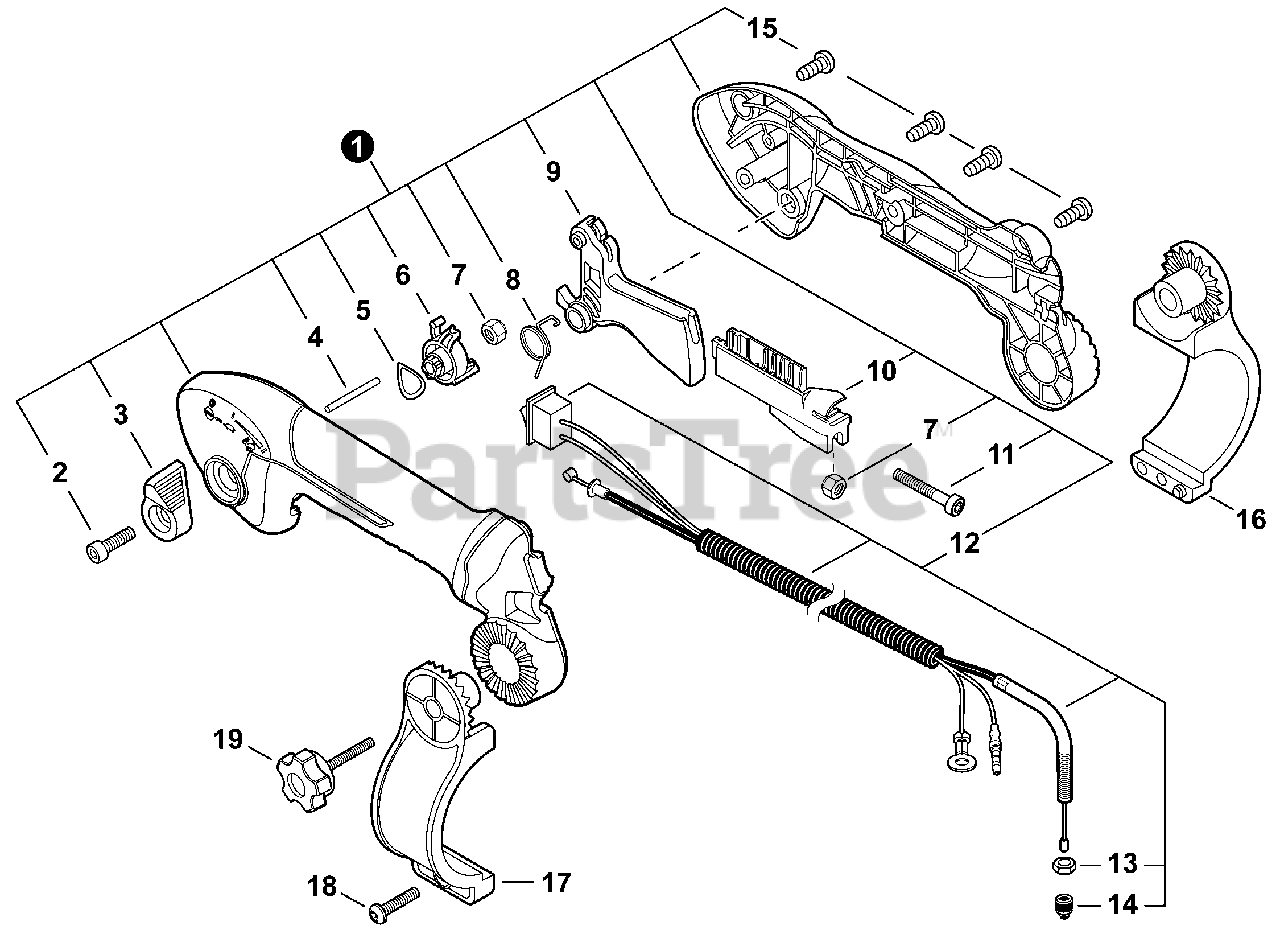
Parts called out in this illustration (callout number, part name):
1	THROTTLE CONTROL KIT - TUBE MOUNT
2	BOLT, TORX 5×20
3	LEVER, THROTTLE
4	PIN 3×32
5	WASHER, WAVE 12
6	CONTROL, THROTTLE
7	NUT, LOCK M5
8	SPRING, TORSION
9	TRIGGER, THROTTLE
10	CONNECTOR, CABLE
11	BOLT, TORX 5×30
12	CABLE ASSY, CONTROL
13	NUT, HEX M6
14	CAP, DUST
15	BOLT, TORX 5×16
16	BRACKET, RIGHT
17	BRACKET, LEFT
18	BOLT, TORX 5×20
19	KNOB, SCREW
